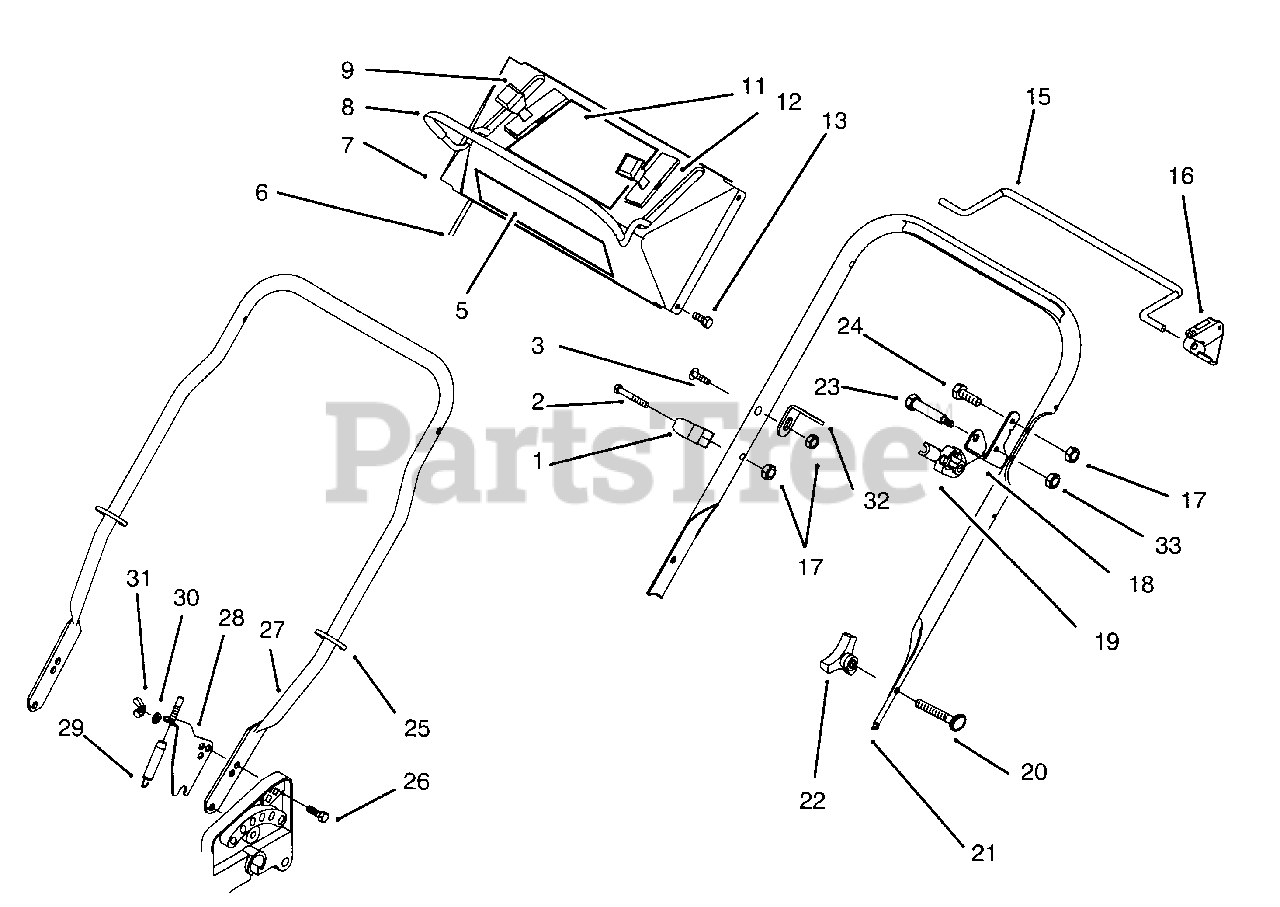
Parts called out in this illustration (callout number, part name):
1	Guide-Rope
5	Decal-Control Panel
6	Cable-Brake
7	Panel-Control (Incl. Ref. # 11) (Model No. 10416)
8	Bail-Brake
9	Control Ground (Model No. 10516 & 10521)
11	Decal-Control Panel, (Model No. 10416)
12	Control-Throttle
15	Bail-Control SP (Model No. 10516 & 10521)
16	Stop-Pivot (Model No. 10516 & 10521)
18	Bracket-Cam
19	Brake-BBC Cam
20	Screw-Handle
21	Handle-Upper
22	Knob-Handle
23	Bolt-Shoulder
24	Screw-Hex. Hd.
25	Tie-Cable
26	Bolt-Carriage
27	Handle-Lower
28	Bracket-Traction Cable (Model No. 10516 & 10521)
29	Cable-Traction (Model No. 10516 & 10521)
32	Bracket-Cable
33	Nut-Lock
